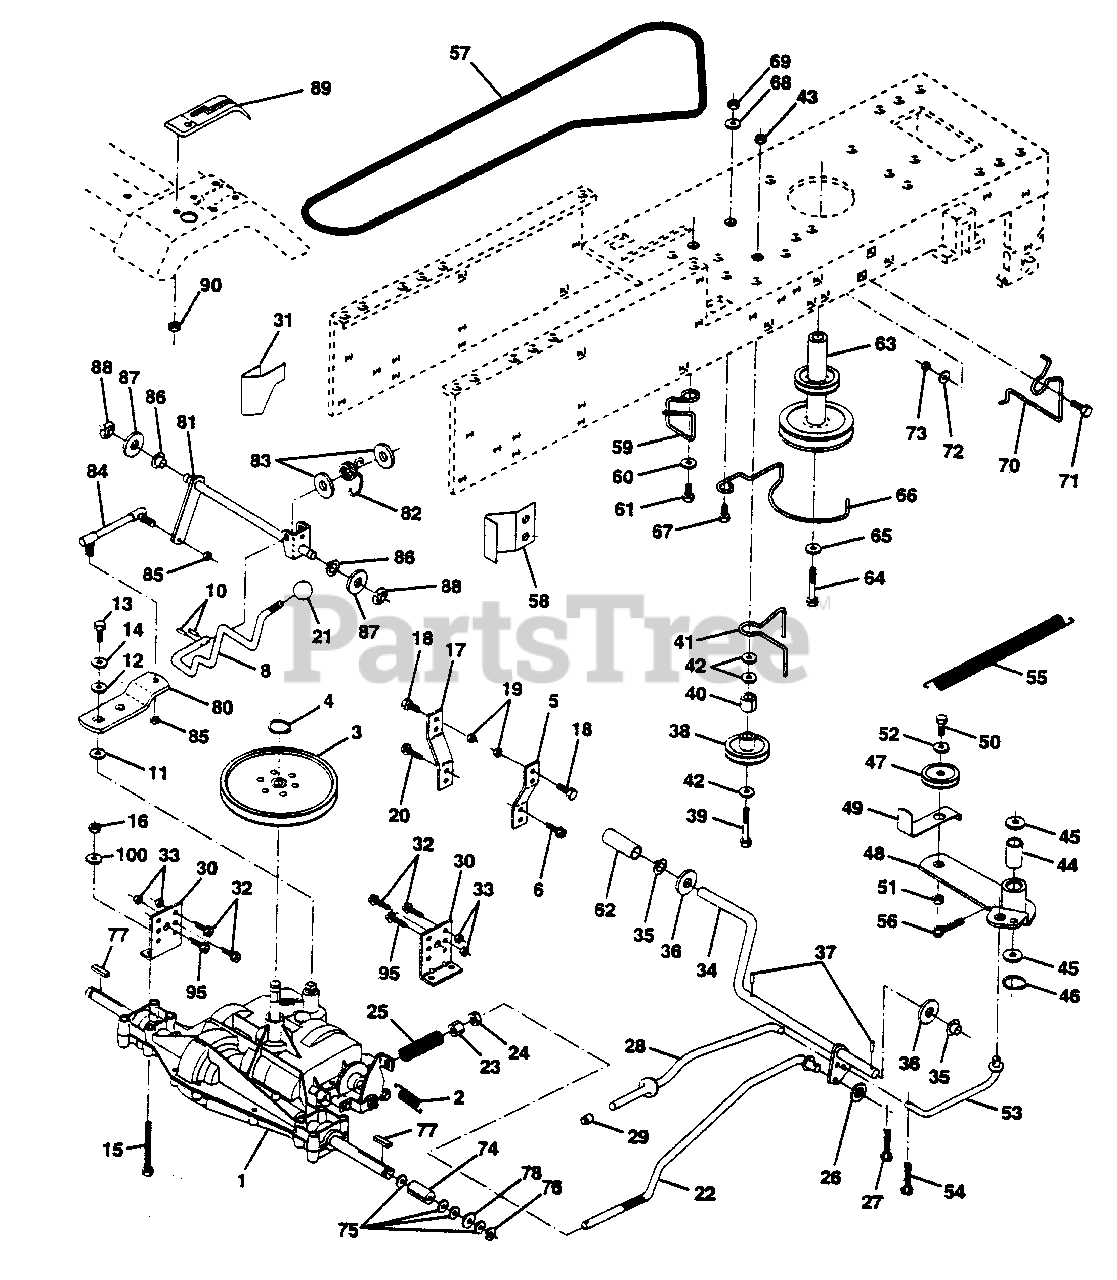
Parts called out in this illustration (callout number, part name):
1	Transaxle 6sp Model No. 4360-79 (AYP part number)
2	Spring Return Brake T/a Zinc (AYP part number)
3	Pulley Transaxle 18" tires (AYP part number)
4	Ring Retainer # 5100-62 (AYP part number)
5	Strap Torque 30 Degrees (AYP part number)
6	Screw Thdrol 5/16-18 X 3/4 TYT
8	Rod Shifter (AYP part number)
10	Pin Cotter 1/8 X 1 Cad (AYP part number)
11	Washer Plate Shf 388 Sq Hole (AYP part number)
12	Washer 9/32 X 3/4 X 10 Ga (AYP part number)
13	Bolt Fin Hex 1/4-28unfx3/4 Gr8 (AYP part number)
14	Washer Lock Hvy Helical 1/4 (AYP part number)
15	Bolt Fin Hex 5/16 - 18 UNC x 2.75 (AYP part number)
16	Nut Hex W/Ins Lock 5/16-18 (AYP part number)
17	Strap Torque LT (AYP part number)
18	Bolt Fin Hex 3/8-16unc X 1 Gr. 5 (AYP part number)
19	Nut Hex Lock W/Ins 3/8-16 Unc (AYP part number)
20	Screw Thdrol 5/16-18 X 3/4 TYT
21	Knob Duckhead 1/2-13 UNC (AYP part number)
22	Rod Brake Blk Zinc 27 326 (AYP part number)
23	Nut Lock Hex W/wsh 3/8-16unc (AYP part number)
24	Nut Hex Jam 3/8-16 Unc (AYP part number)
25	Spring Rod Brake 2 00 Zinc (AYP part number)
26	Washer 13/32 X 13/16 X 16 Ga (AYP part number)
27	Pin Cotter 1/8 X 3/4 Cad (AYP part number)
28	Rod Brake Parking LT (AYP part number)
29	Cap Brake Parking Black (AYP part number)
30	Bracket Mtg Transaxle (AYP part number)
31	Keeper Belt LH LT 14 Ga (AYP part number)
32	Bolt Hex Hd 5/16-18unc X 3/4 (AYP part number)
33	Nut Hex W/Ins Lock 5/16-18 (AYP part number)
34	Shaft Asm Pedal Foot 1 930 (AYP part number)
35	Bearing Nylon Blk 629 ld (AYP part number)
36	Washer 21/32 X 1 X 16 Ga (AYP part number)
37	Pin Roll 3/16 X 1" (AYP part number)
38	Pulley Idler Flat (AYP part number)
39	Bolt Fin Hex 3/8-16unc X 2-3/4 (AYP part number)
40	Spacer Split 395 X 59 Bzp (AYP part number)
41	Keeper Belt Retainer (AYP part number)
42	Washer 13/32 X 13/16 X 12 Ga (AYP part number)
43	Nut Lock Hex W/Ins 3/8-16 Unc (AYP part number)
44	Bearing Nyl 503 X 628 X 1 25 (AYP part number)
45	Washer Hardened (AYP part number)
46	Ring Klip #t5304-50 (AYP part number)
47	Pulley Idler V Groove Plastic
48	Bellcrank Asm Clutch (AYP part number)
49	Retainer Belt Style Spring (AYP part number)
50	Bolt Hex Hd 3/8-16unc X 1-1/2 (AYP part number)
51	Nut Crownlock 3/8-16 Unc
52	Washer 13/32 X 13/16 X 16 Ga (AYP part number)
53	Link Clutch 7 66 (AYP part number)
54	Pin Cotter 1/8 X 3/4 Cad (AYP part number)
55	Spring Return Clutch 6 75 (AYP part number)
56	Pin Cotter 1/8 X 3/4 Cad (AYP part number)
57	V-Belt Ground Drive 95 25 42" (AYP part number)
58	Keeper Belt RH LT Pnt/zinc 16g (AYP part number)
59	Keeper Belt Chassis Span Ctr (AYP part number)
60	Washer 13/32 X 13/16 X 12 Ga (AYP part number)
61	Screw Thdrol 3/8-16x3/4 Ty-tt (AYP part number)
62	Cover Pedal Blk Round (AYP part number)
63	Engine Pulley (AYP part number)
64	Bolt Hex 7/16-20x4 Gr 5 (AYP part number)
65	Washer Lock Hvy Hlcl Spr. 7/16 (AYP part number)
66	Keeper Belt Engine LH LT (AYP part number)
67	Bolt Fin Hex 3/8-16unc X 1 (AYP part number)
68	Washer 13/32 X 13/16 X 12 Ga (AYP part number)
69	Nut Crownlock 3/8-16 Unc
70	Guide Belt Mower Drive RH (AYP part number)
71	Bolt Fin Hex 3/8-16unc X 1 (AYP part number)
72	Washer 13/32 X 1-1/4 X 12 Ga (AYP part number)
73	Nut Crownlock 3/8-16 Unc
74	Spacer Axle (AYP part number)
75	Washer 25/32 X 1 1/4 X 16 Ga. (AYP part number)
76	E-ring #5133-75 (AYP part number)
77	Key Square 2 0 X 1845/ 1865 (AYP part number)
78	Washer 25/32 X 1-5/8 X 16 Ga. (AYP part number)
80	Arm Shift Transaxle (AYP part number)
81	Shaft Asm. Cross 18" + 42" Deck (AYP part number)
82	Spring Torsion T/A (AYP part number)
83	Washer 17/32 x 3/4 x 16 Ga. (AYP part number)
84	Rod Shift Adj. Tie (AYP part number)
85	Nut Nylock 1/4-28 (AYP part number)
86	Bushing Rod Strg. 629/632 ld (AYP part number)
87	Washer 21/32 x 1 - 1/4 x 16 Ga. (AYP part number)
88	Ring Klip #5304 - 62 (AYP part number)
89	Console Shift 6 st LT (AYP part number)
90	Nut Self-thd Wsh-hd 1/4 Zinc (AYP part number)
95	Screw Thdrol 3/8 - 16 x 3/4 (AYP part number)
100	Washer 11/32 x 3/4 x 16 Ga. (AYP part number)
